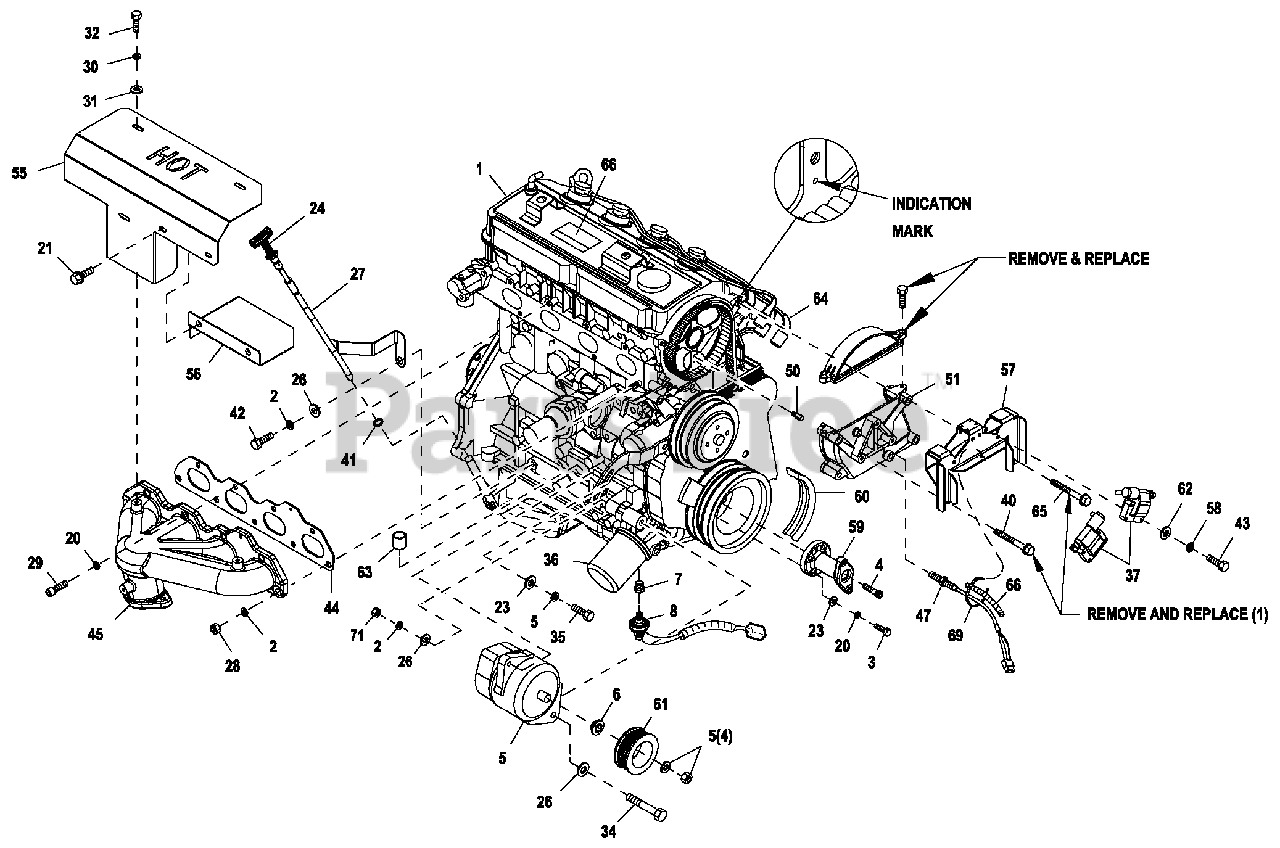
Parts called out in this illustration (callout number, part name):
1	ROTOR-2390-45KD1 CPL
2	ROTOR-2390-35KD1 CPL
3	ROTOR-2390-45KD1 CPL (G2)
4	ROTOR-2390-35KD1 CPL (G2)
5	ROTOR 25KW 3PH DIRECT 390 1800
6	ROTOR 25KW 1PH DIRECT 390 1800
7	ADAPTOR 1/8 NPTF TO 1/8 BSPT
8	HARN LOW OIL PRESS SWITCH ASSY
20	WASHER LOCK M8-5/16
21	STATOR-390 45K 2P 1PH DIRECT
23	STATOR-2390-35AD1 CPL
24	STATOR-2390-35KD1 CPL
26	STATOR-2390-35GD1 CPL
27	STATOR-2309-45KW 2P 3PH 208V
28	STATOR-2309-45-KD1 CPL
29	SCREW SHC M8-1.25 X 25 G12.9
30	WASHER LOCK M6-1/4
34	SCREW HHC M10-1.5X 120 C8.8
35	SCREW HHC M8-1.25X 25 G10.9
36	FILTER 1.5L/2.4LG2 OIL
37	COIL-2.4LG2 IGNITION
41	O-RING SIZE 9.0MM X 2.0MM NITR
42	SCREW HHC M10-1.25X 20 C8.8
43	SCREW HHM # 10 -3 2X 1 -1 /4
44	GASKET EXHAUST MANIFOLD
45	EXHAUST MANIFOLD G2 (MACHINE)
47	ASSY MAGPICKUP(3/8-24 MALE)
50	CAM SENSOR PIN ASSY
51	COVER CAM GEAR G2 REWORKED
55	SHIELD HEAT
56	SHIELD HEAT SML
57	BRACKET ASM-2.4L COIL G2
58	WASHER LOCK #10
59	ADAPTER 2.4L CRANKSHAFT MACH
60	POLY V-BELT G2
61	PULLEY DC ALTERNATOR
63	PLUG TAPER
64	SPARK PLUG WIRE SET 2.4L G2 IG
65	SCREW HHC M8 -1 .25X70 G8.8
66	CONDUIT FLEX .25 "ID
69	TIE WRAP UL 7.4"X .19" BLK
71	NUT HEX M10-1.5 G8 YEL CHR
